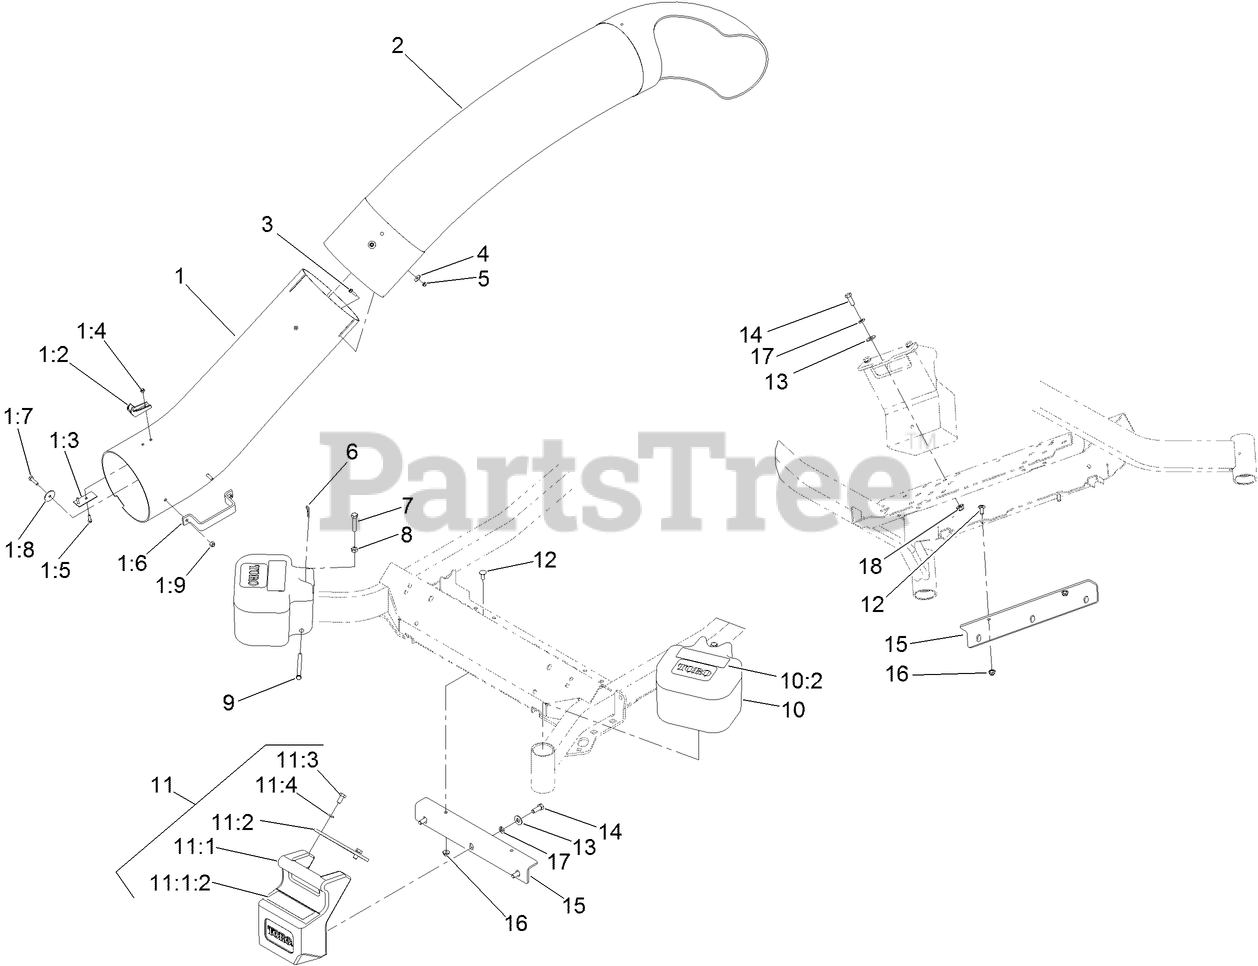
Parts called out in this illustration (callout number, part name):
1	LOWER TUBE ASM
1:2	LATCH-CATCH
1:3	PLATE-BACKING
1:4	NUT-LOCK, NI
1:5	SCREW-HWH
1:7	SCREW-HH
1:8	WASHER-FLAT
1:9	NUT-LOCK, NI
2	TUBE-UPPER
3	SCREW-HWH
4	WASHER-FLAT
5	NUT-LOCK, NI
6	PIN-COTTER
7	SCREW-HH
8	NUT-HEX
9	PIN-CLEVIS
10	63 LBS WEIGHT ASM
10:2	Decal-Warning, Counterweight
11	WEIGHT ASM
11:1	WEIGHT
11:1:2	Decal-Warning, Counterweight
11:2	TAB-SUPPORT, WEIGHT
11:3	SCREW-HH
11:4	WASHER-LOCK
12	SCREW-CARR
13	WASHER-FLAT
14	SCREW-HH
15	BRACKET-MOUNT, WEIGHT
16	NUT-HF, NI
17	WASHER-LOCK
18	NUT-HF, NI
